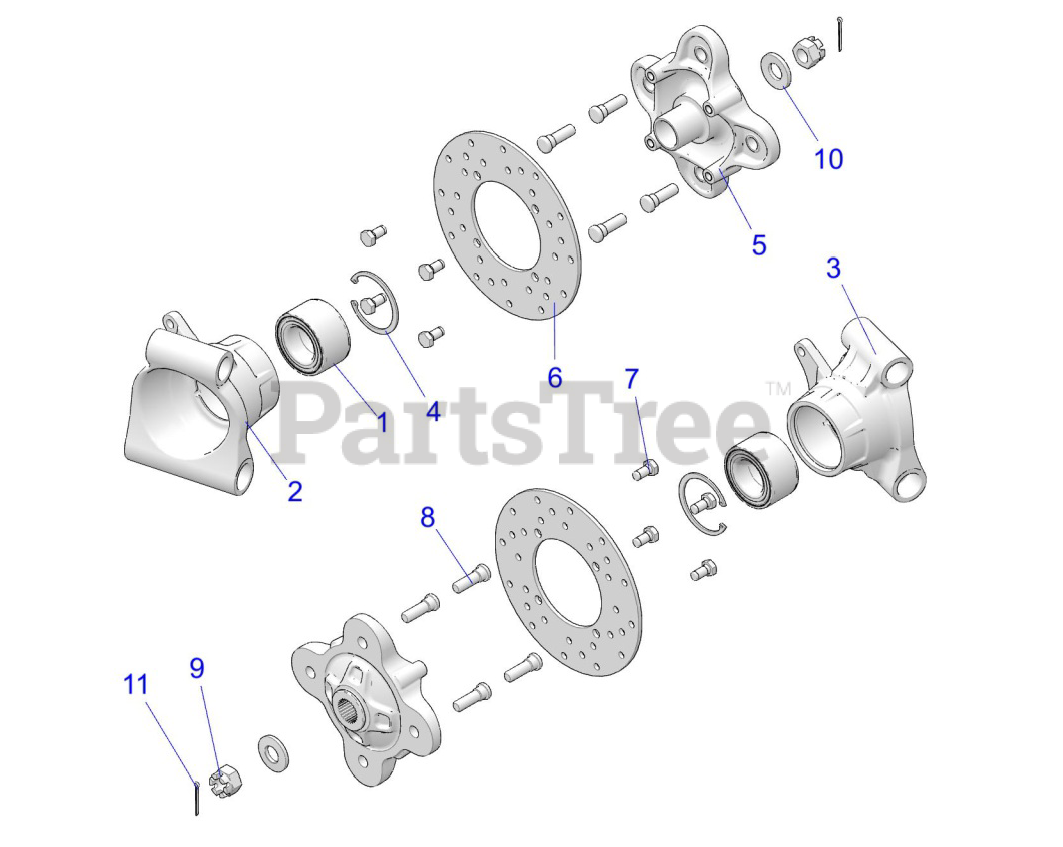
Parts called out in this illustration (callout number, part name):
1	BEARING-WHEEL,40X74X40MM
2	CARRIER-BEARING,LH
3	CARRIER-BEARING,RH
4	RING,RETAINING
5	HUB-WHEEL,MACH,BLK
6	DISC-BRAKE,REAR,8.625X.188 (Rotor)
7	SCR-M10X1.5X20,8.8 ZY3
8	STUD-WHEEL,M12-1.5
9	NUT-M18X1.5,CASTLE,ZINC/YELLOW
10	WSHR-AXLE,M18,42X4.5
11	PIN, COTTER
